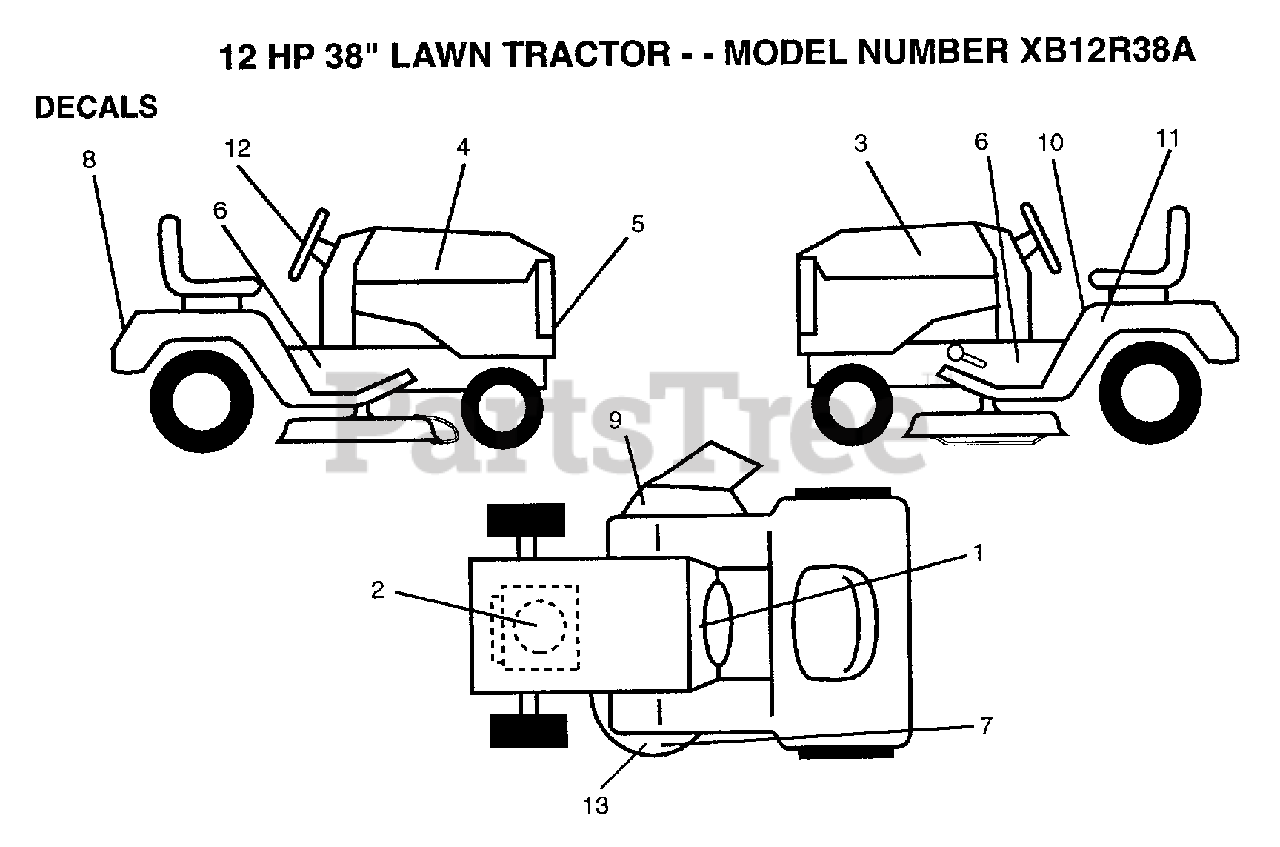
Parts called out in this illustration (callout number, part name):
2	DECAL.ENG.271967
3	DECAL HOOD LH
4	"DECAL,HOOD RH "
5	"DECAL,GRILL "
6	DECAL, SPEED/DECK SIZE, CHASSIS
7	DECAL YT
8	DECAL, FENDER
9	DECAL WARNING
10	DECAL CAUTION
11	IND HGT DECK DECA
12	"DECAL,STR WHL "
13	"DECAL,ENVIRO DECK"
